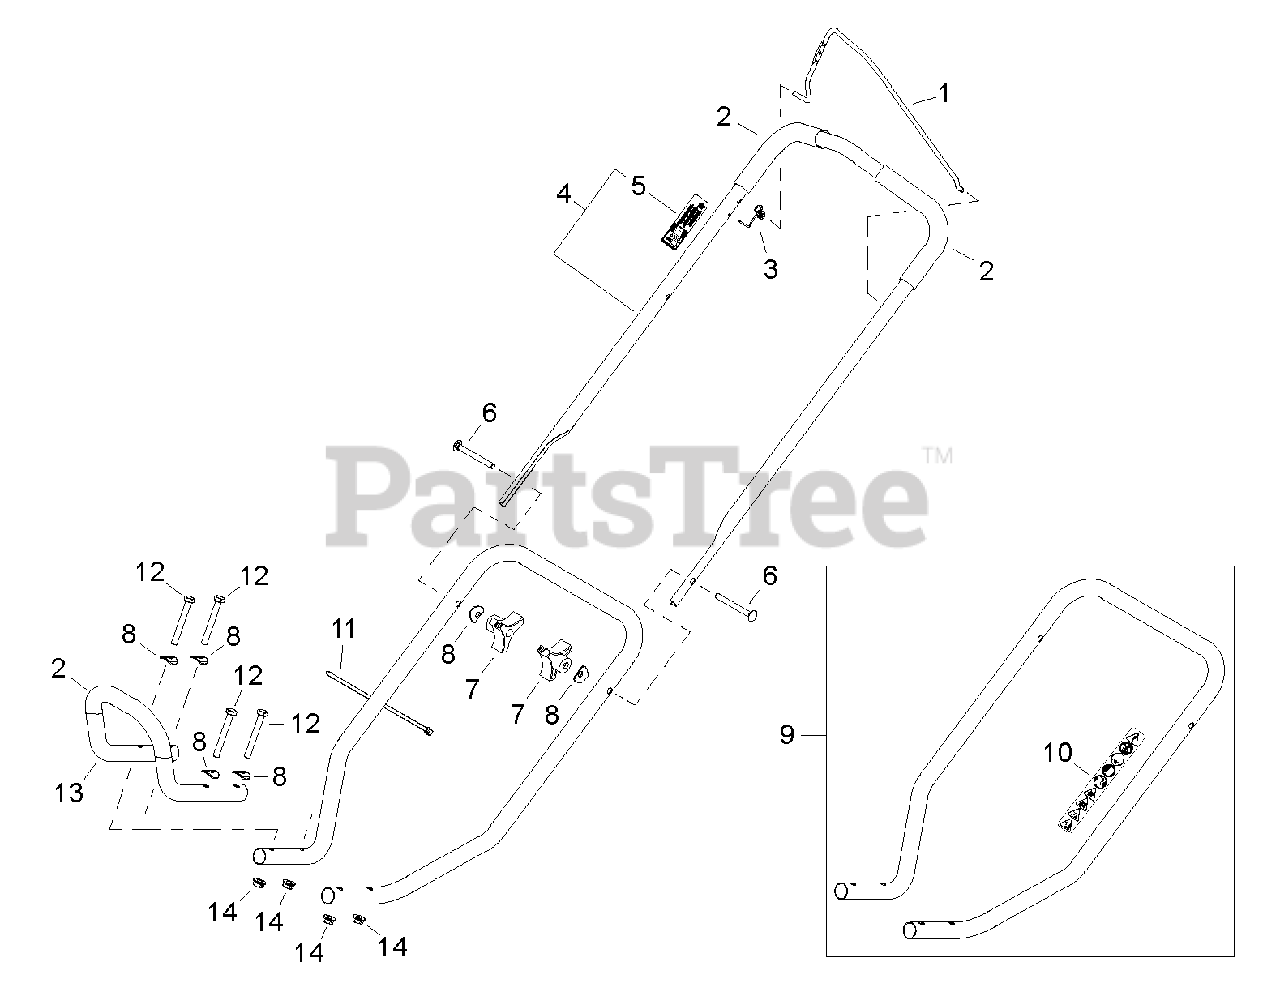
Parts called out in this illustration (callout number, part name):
1	BAIL - THROTTLE CONTROL
2	FOAM GRIP
3	TORSION SPRING
4	HANDLE ASSY - UPPER
5	LABEL - IGNITION SWITCH
6	BOLT
7	KNOB
8	SHOULDER WASHER
9	HANDLE ASSY - LOWER
10	LABEL - CAUTION
11	TIE, CABLE
12	SCREW
13	HANDLE - FRONT
14	LOCKNUT
